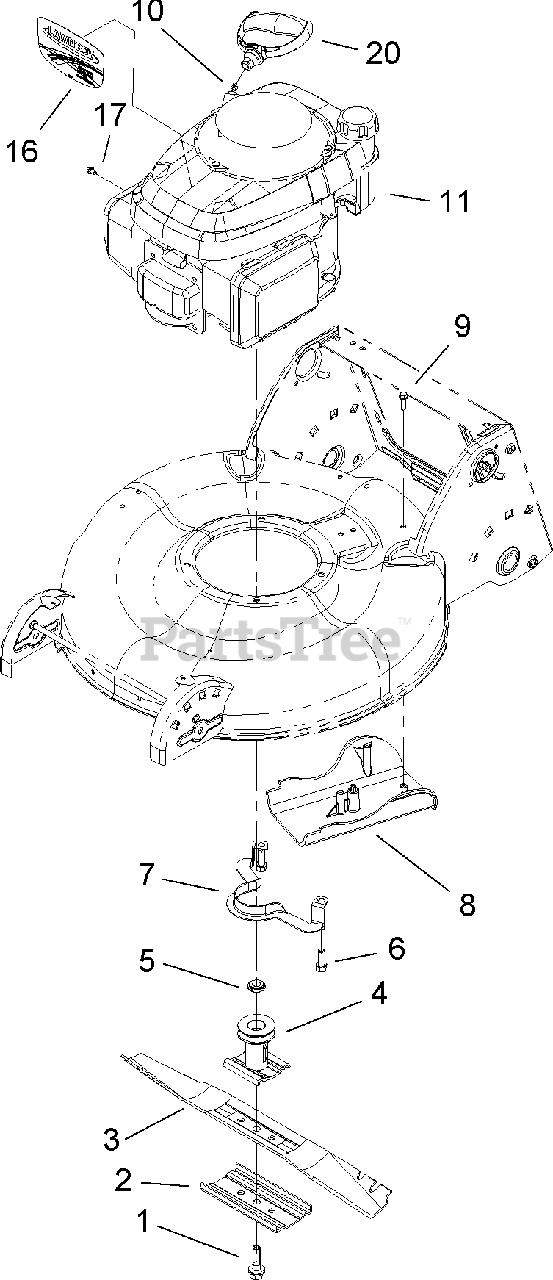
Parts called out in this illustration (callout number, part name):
1	BOLT-BLADE
2	SUPPORT-BLADE
3	BLADE-21 INCH
4	BLADE DRIVER ASM
5	Spacer-Driver
6	SCREW
8	COVER-BELT
9	SCREW-HWH
10	STOP-ROPE
17	SCREW-HWH
20	HANDLE-RECOIL
